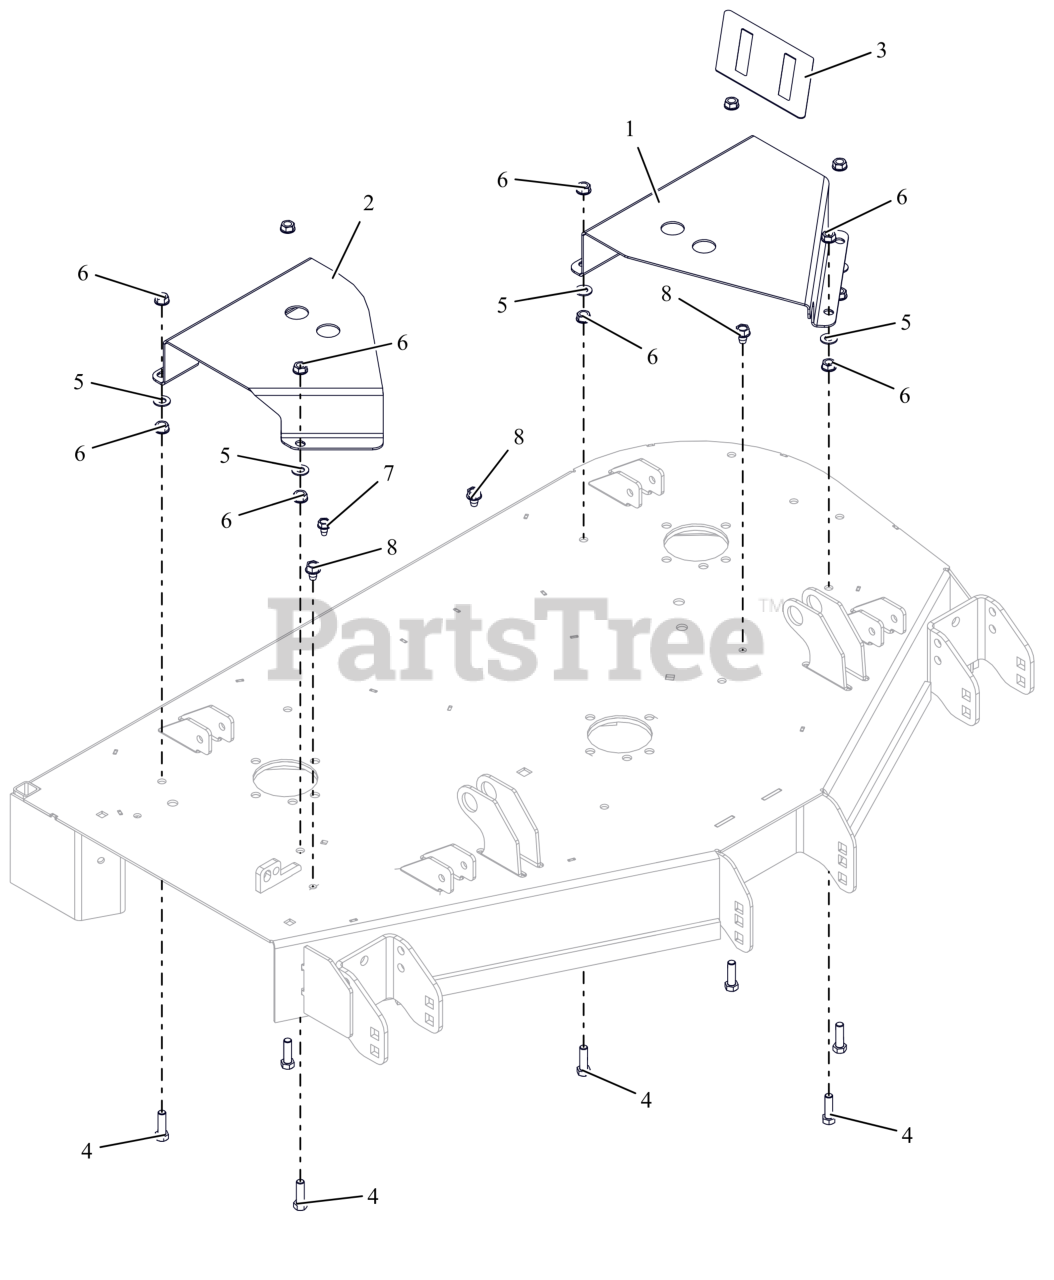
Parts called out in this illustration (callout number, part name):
1	COVER, BELT 44" LH
2	COVER, BELT 44" RH
3	GRIP, TAPE 44 BELT COVER
4	BLT, HEX .38-16X1.25 G5 ZCC
5	WSHR,FLT .406X.812X.065 ZCC
6	NUT, SPNLK-FLG .38-16 G5 ZCC
7	SCR,TAP .312-18X.50 HWH TR ZCC
8	SCR,TAP .375-16X.50 HWH TR ZCC
